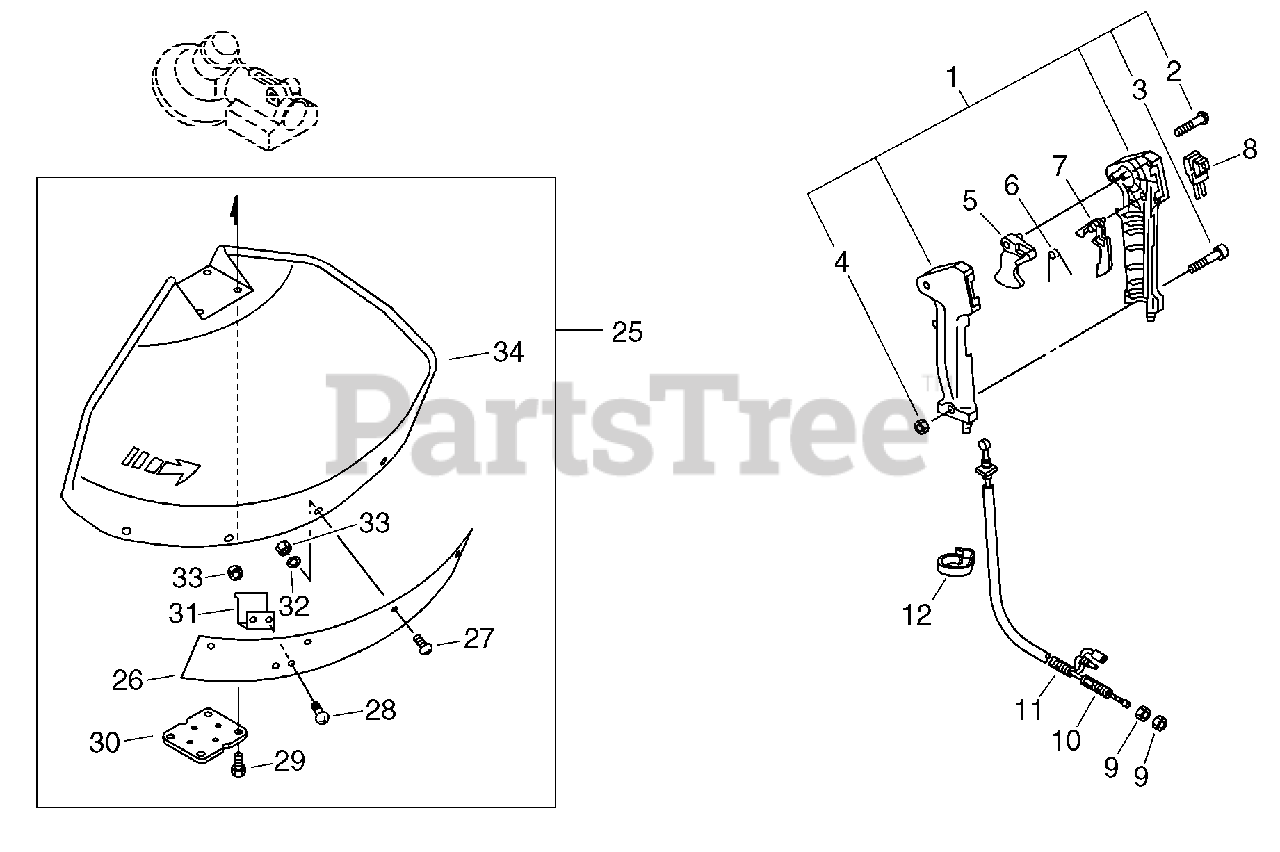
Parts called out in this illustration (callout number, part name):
1	THROTTLE CONTROL ASSY
2	SCREW - 3X25
3	SCREW - 5X30
5	TRIGGER, THROTTLE
6	SPRING, LOCKOUT LEVER
7	LOCKOUT, THROTTLE
8	IGNITION SWITCH ASSY
10	CABLE, THROTTLE
25	DEBRIS SHIELD ASSY
26	GUARD, SHIELD
27	SCREW - 5X18
28	SCREW - 5X14
29	BOLT - 5X25
30	BRACKET, SHIELD
31	KNIFE, TRIMMER LINE
32	WASHER - 5
34	SHIELD, DEBRIS
